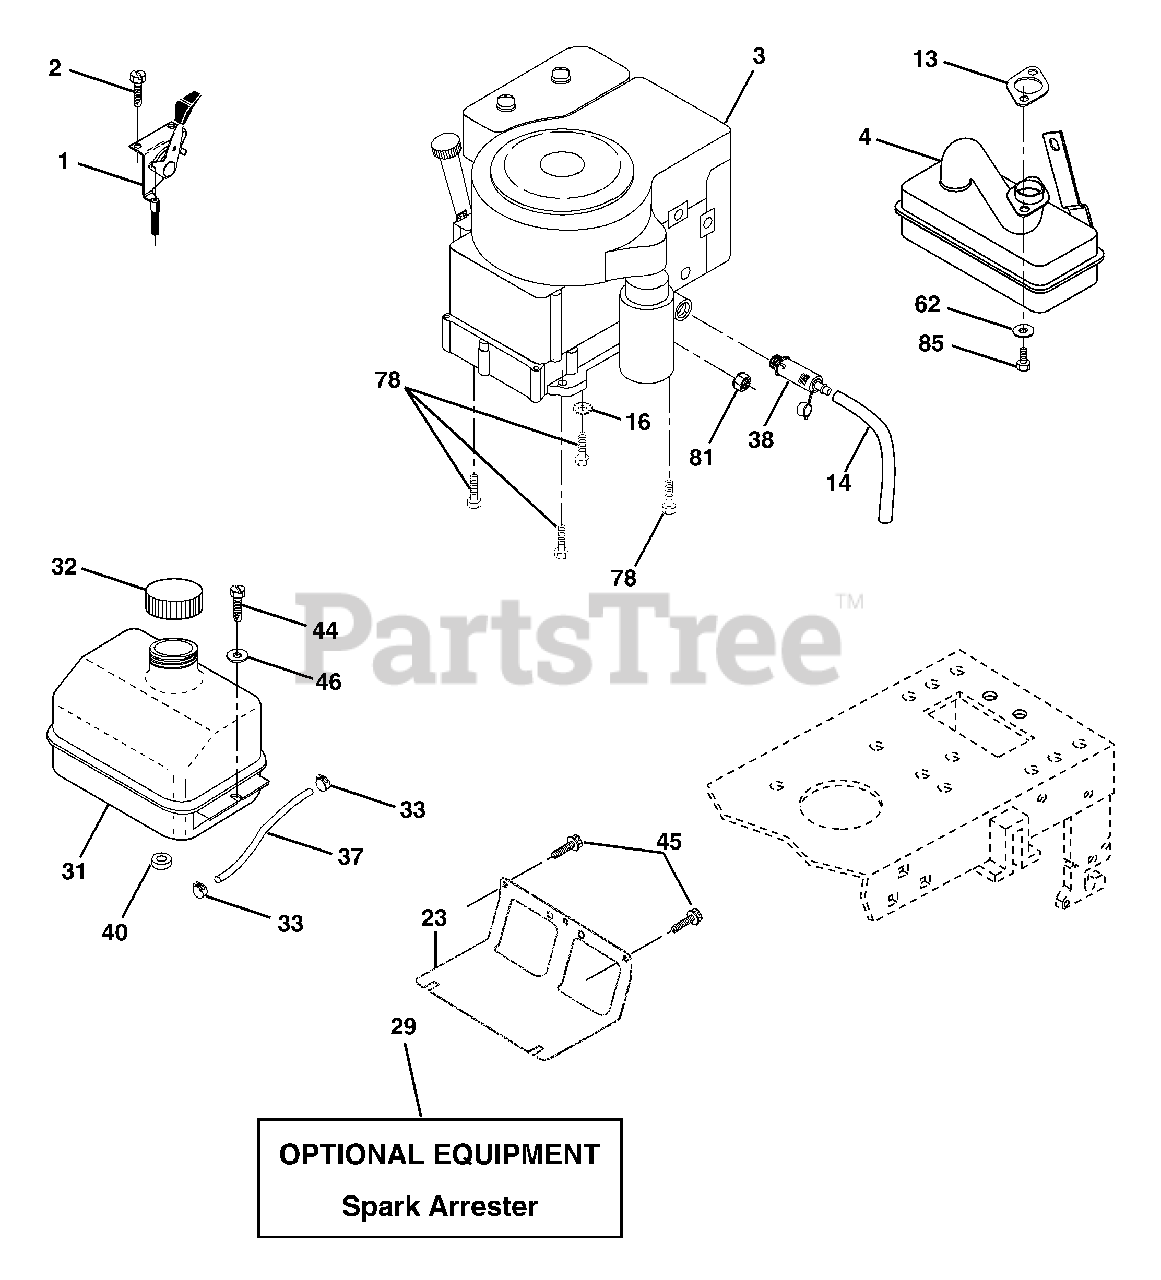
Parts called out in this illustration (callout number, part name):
1	Control Th/ch Flag
2	Screw Hex Thd Cut 1/4-20 x 1/2
4	Muffler Exhaust
13	Gasket Eng
14	Tube Drain Oil Easy
16	Washer Lock Ext Tooth 3/8
23	Shield BRN/DBR Guard
29	Kit Spark Arrestor (Flat Scrn)
31	Tank Fuel Front
32	Cap Asm Fuel
33	Clamp Hose
37	Line Fuel 20"
38	Plug Drain Oil
40	Bushing Snap Nyl Blk Fuel Line
44	Screw Thdrol 1/4-20 x 3/4
45	Screw Hex Wsh Thdrol 3/8-16
46	Washer 9/32 x 7/8 x 16 Ga
62	Washer Lock Hvy HLCL Spr. 5/16
78	Screw 3/8-16 x 1-1/4
81	Nut Keps Hex 1/4-20 Unc
85	Bolt Hex Hd Phillips
